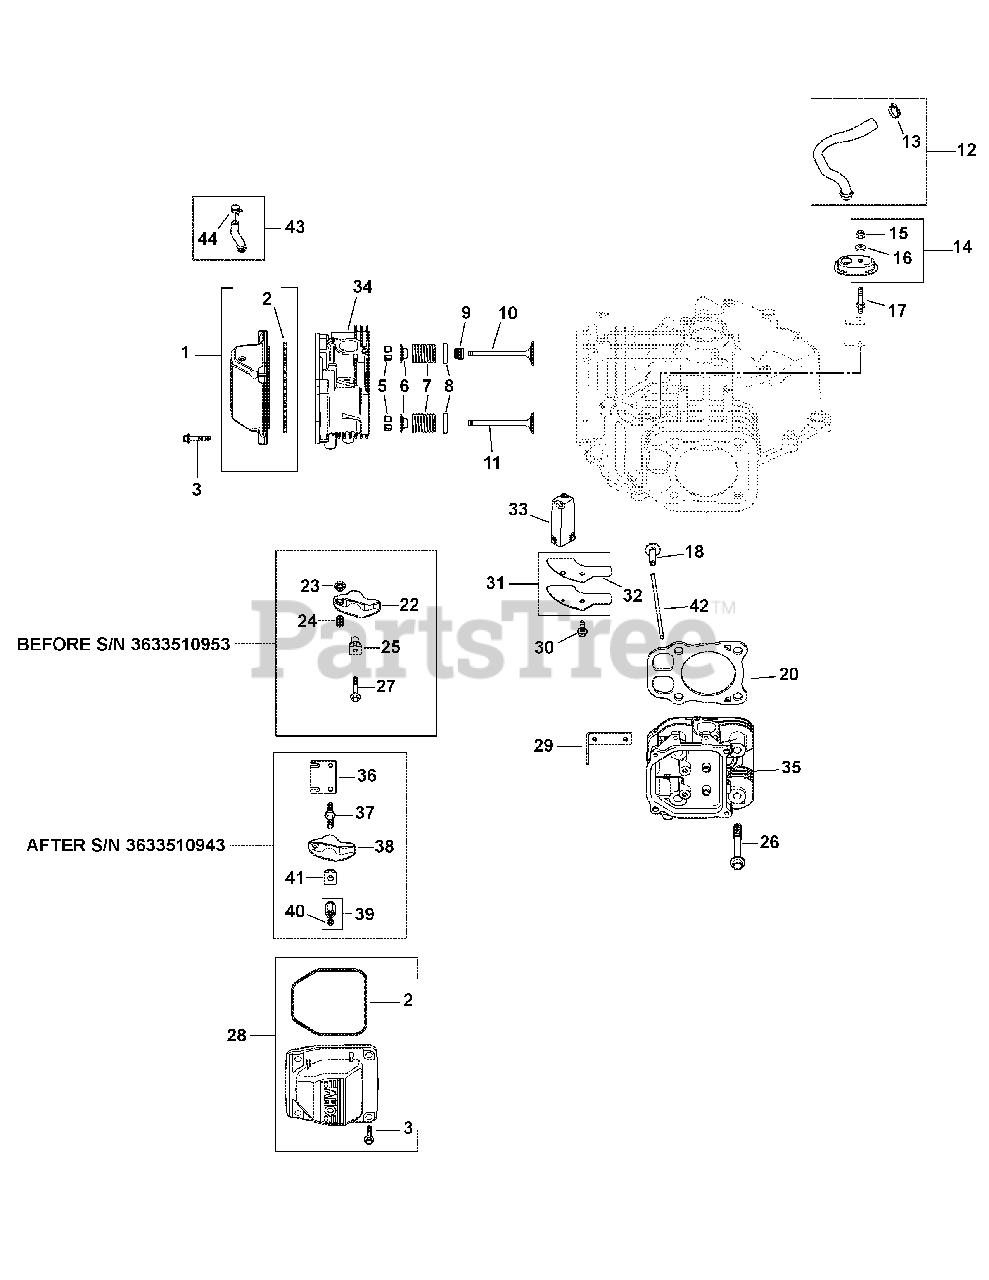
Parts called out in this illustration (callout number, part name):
1	Breather Valve Cover Kit
2	Valve Cover O-Ring
3	Flg. Screw, M6 x 1.0 x 30
6	Valve Spring Cap
8	Spring Retainer
9	Valve Stem Seal
11	Exhaust Valve
12	Breather Hose Kit
13	Hose Clamp, 1.2
14	Breather Housing Kit
15	Lock Nut, M5 x .8
16	Sealing Washer
17	Breather Cover Stud
20	Cylinder Head Gasket Kit
22	Fuse Block
23	Fuse Block
24	Fuse Block
25	Fuse Block
26	Flg. Screw, M10 x 1.5 x 90
27	Fuse Block
28	Breather Valve Cover Kit
29	Lifting Strap
30	Flg. Thd. Frm. Screw, M6 x 1.0 x 16
31	Breather Cover Kit
32	Fuse Block
33	Breather Filter
34	#1 Cylinder Head Assembly Kit
35	#2 Cylinder Head Assembly Kit
39	Hex Nut Assembly
41	Rocker Arm Pivot
43	Fuel Pump Hose Kit w/Clamp
